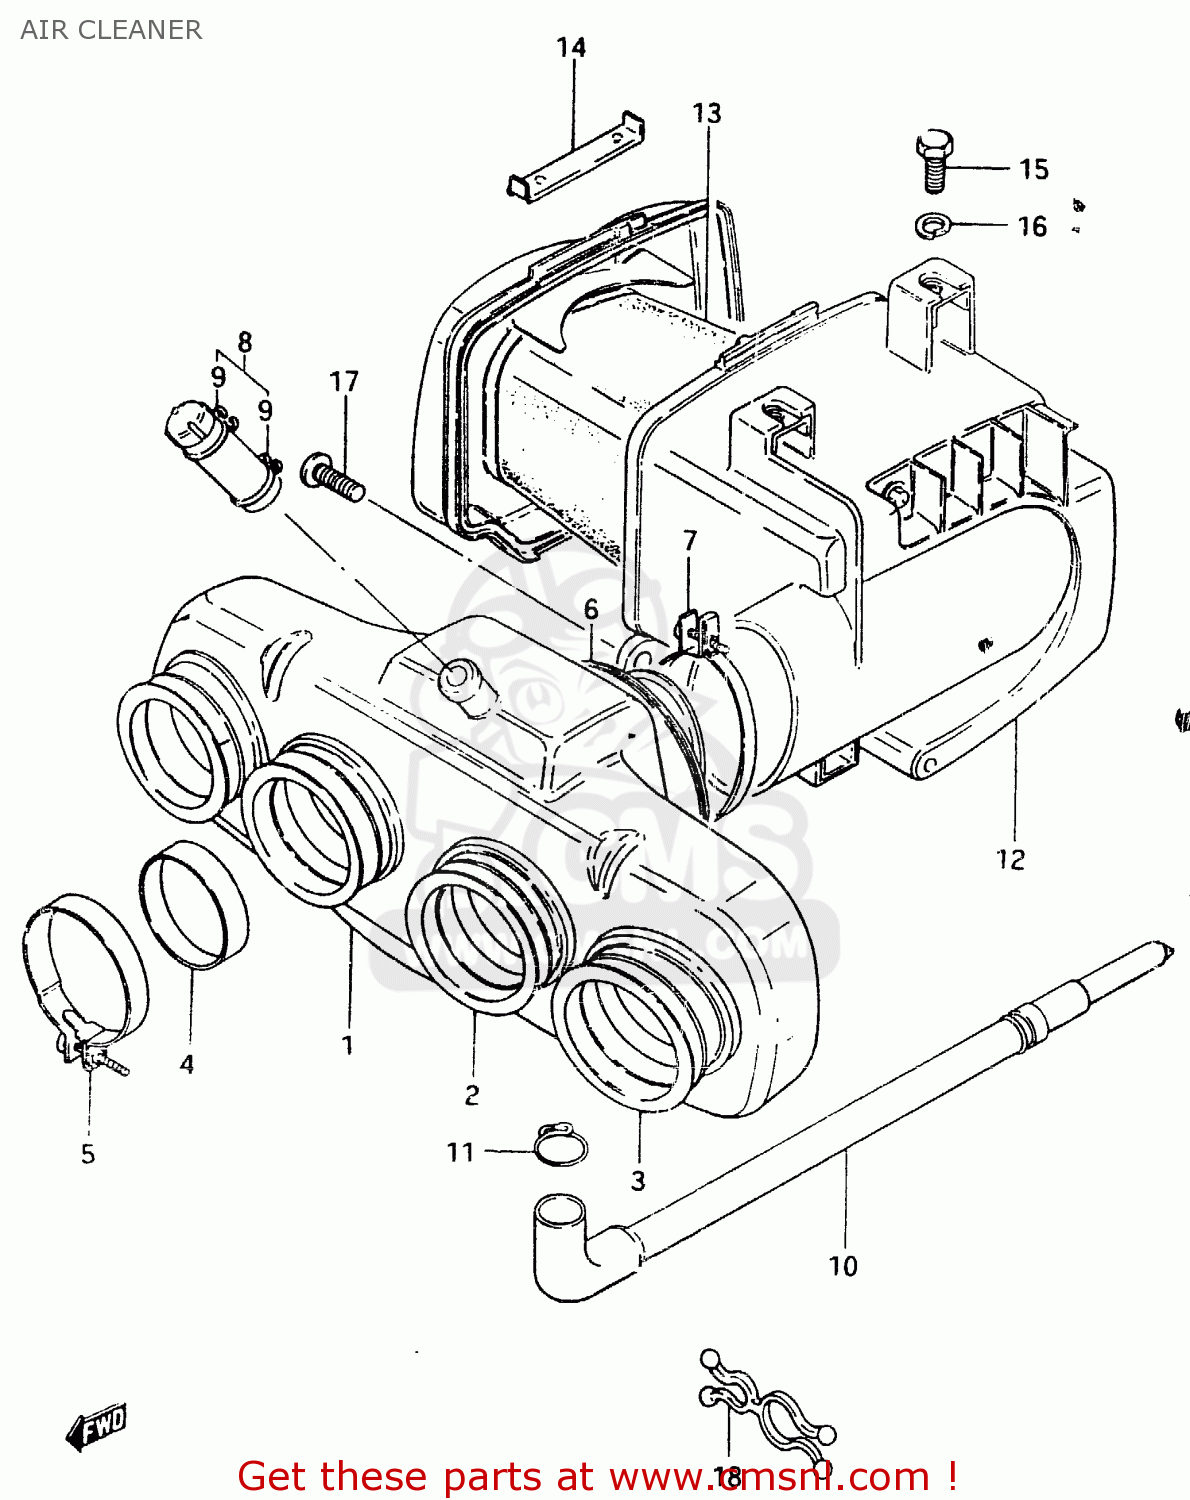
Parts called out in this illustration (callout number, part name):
1	CASE ASSY, FRONT
2	TUBE,INNER
3	TUBE,OUTER
4	RING,CARBURETOR AIR IN
5	CLAMP
6	JOINT,HOSE AIR CLEANER
7	CLAMP
8	TUBE, BREATHER
9	CLIP,BREATHER TUBE
10	TUBE, DRAIN
11	CLIP
12	CASE SET, REAR
13	FILTER ASSY
14	SLIDER
15	BOLT, UPPER
16	LOCK WASHER
17	SCREW
18	CLAMP
